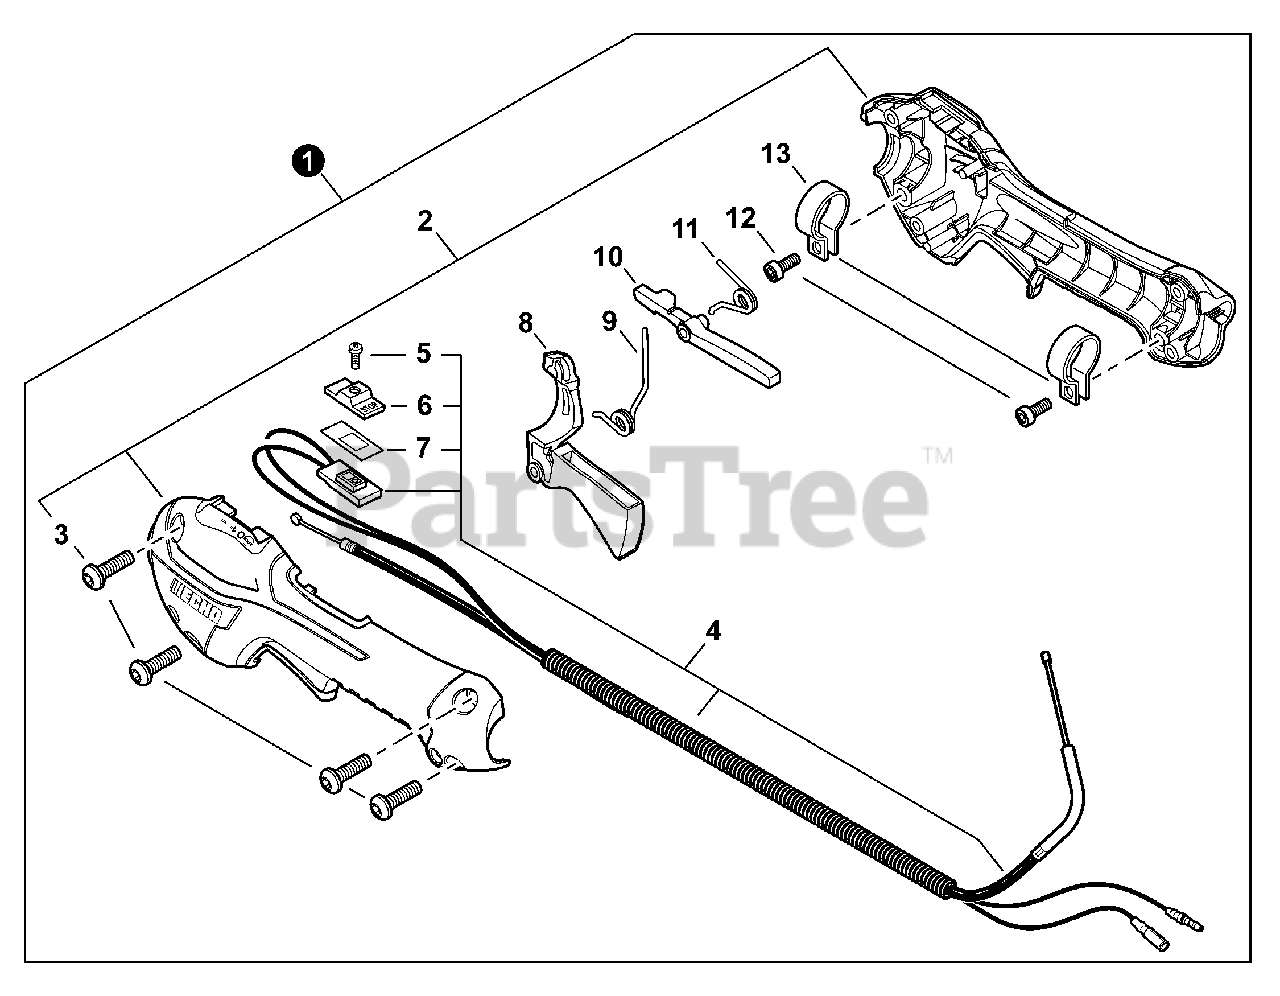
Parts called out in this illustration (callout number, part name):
1	CONTROL HANDLE ASSY
2	CONTROL HANDLE KIT
3	BOLT, TORX 5×16
4	CABLE ASSY, CONTROL
5	SCREW 3×10
6	KNOB, SWITCH - ORANGE
7	SEAL, SWITCH
8	TRIGGER, THROTTLE
9	SPRING, TORSION
10	LEVER, THROTTLE LOCKOUT
11	SPRING, TORSION
12	BOLT, TORX 5×16
